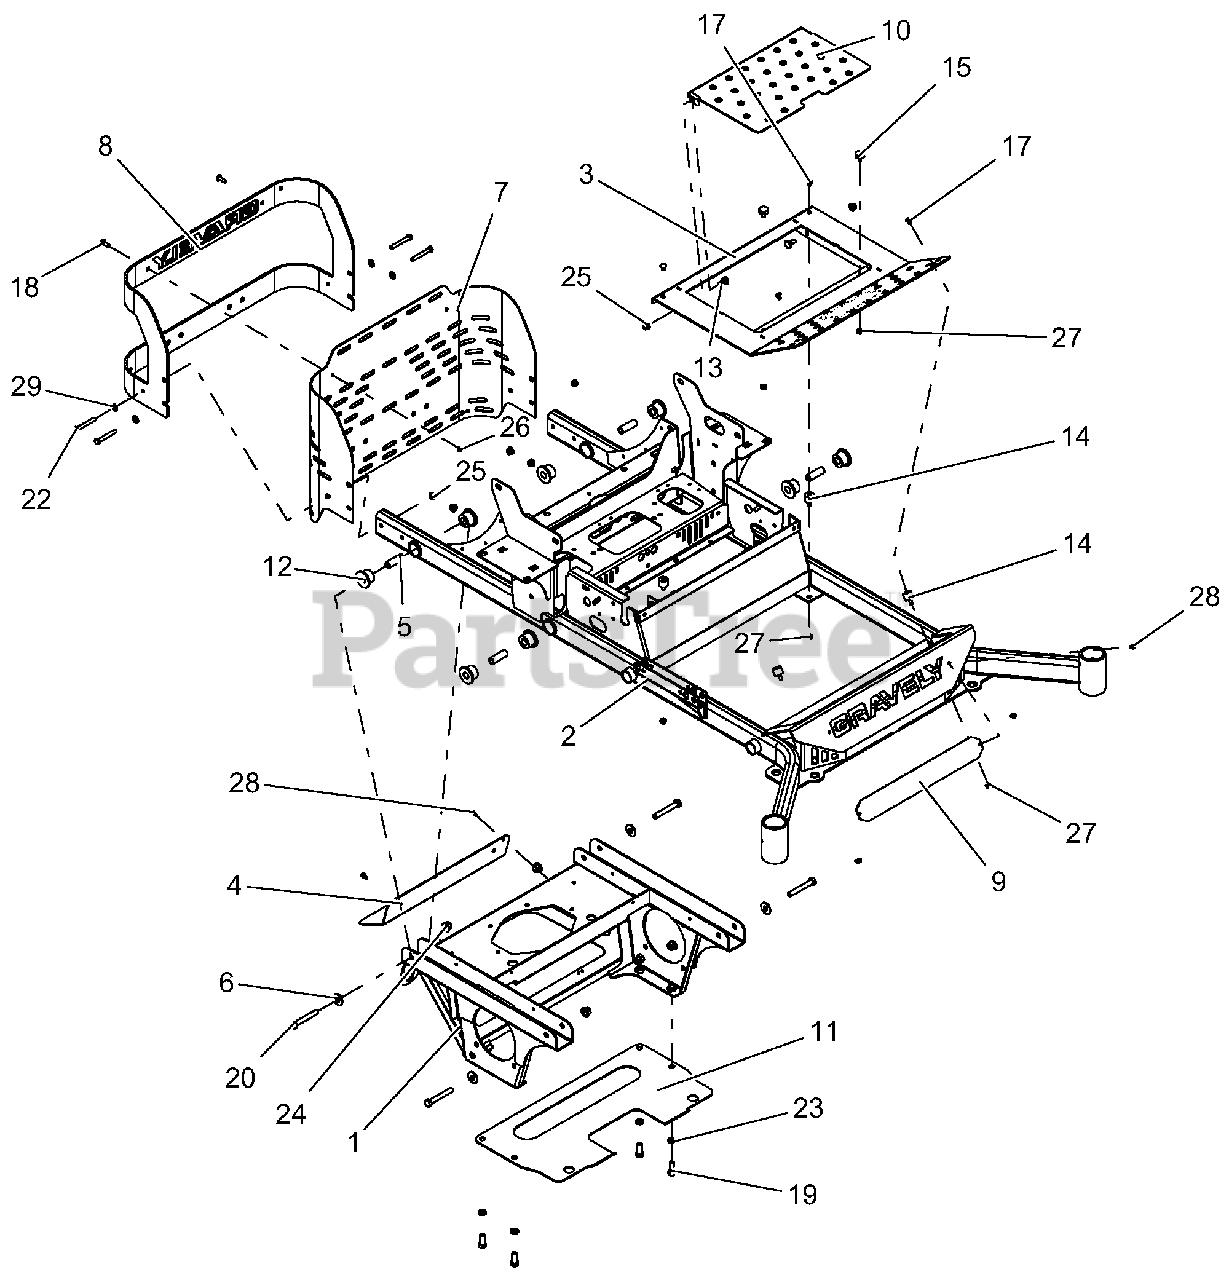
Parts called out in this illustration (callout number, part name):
1	WLDT, 200 PT AXLE/ENGINE FRAME
2	72" PT200/400 MAIN FRAME WITH SAFTEY DECALS
3	FOOTPLATE WLDMT W/SAFETY DECAL
4	SHIELD, MUFFLER HEAT-BLACK
5	SPCR, .50 X .75 X 2.23 YZ
6	WSHR-FL-STL.563X1.38X.109YWZC
7	GUARD, REAR BUMPER FINGER-BLACK
8	REAR BUMPER W/SAFETY DECALS-GAS
9	PLATE, BUMPER LOGO BACKING-BLACK
10	INSPECTION PANEL W/SAFETY DECAL
11	PLATE-TRANSMISSION SKID-RED
12	BSHG, FLG .75 X 1.51 X 2.00 X .18
13	BLT, SHLDR EP .38-16X.30 HEX YZ
14	BUMPER, STUD MOUNTED W/FEMALE INSERT
15	BUMPER, RUBBER
17	BLT-RDHDSQNK .31-18X.50 G5 YWZC
18	BLT-RDHDSQSHNK .31-18X1.00 G5YWZC
19	BLT-HEX .50-13X1.25 GR5 YWZC
20	BLT-HEX .50-13X3.50 GR5 YWZC
22	BLT-HEX .38-16X2.75 GR5 YWZC
23	WSHR-LK .50X.125 REG YWZC
24	NUT-LK-NYL-FLG .50-13 YWZC
25	NUT-LK-NYL-FLG .38-16 YWZC
26	NUT-LK-NYL-FLG .31-18 YWZC
27	@NUT-SPNLK-FLG .312-18 YWZC
28	SCR-TAP .25-20X.50 HWH TR YWZ
29	WSHR-FL-STL.406X.812X.065 YWZ
